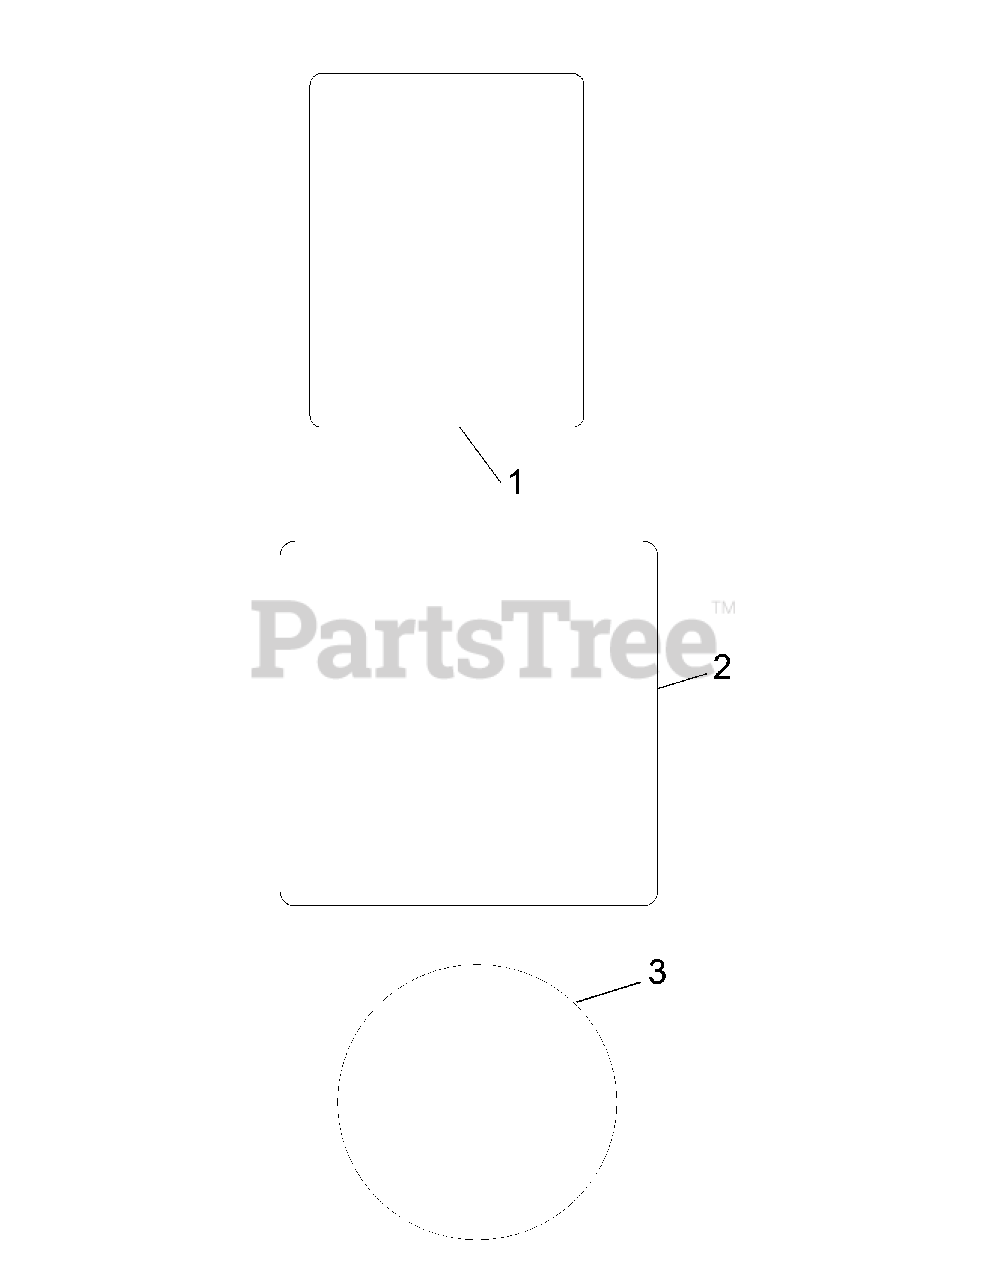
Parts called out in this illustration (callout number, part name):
1	Clear Laminate Decal
2	HDAC 747cc/CV-CH732 Decal
3	Grass Screen Decal
